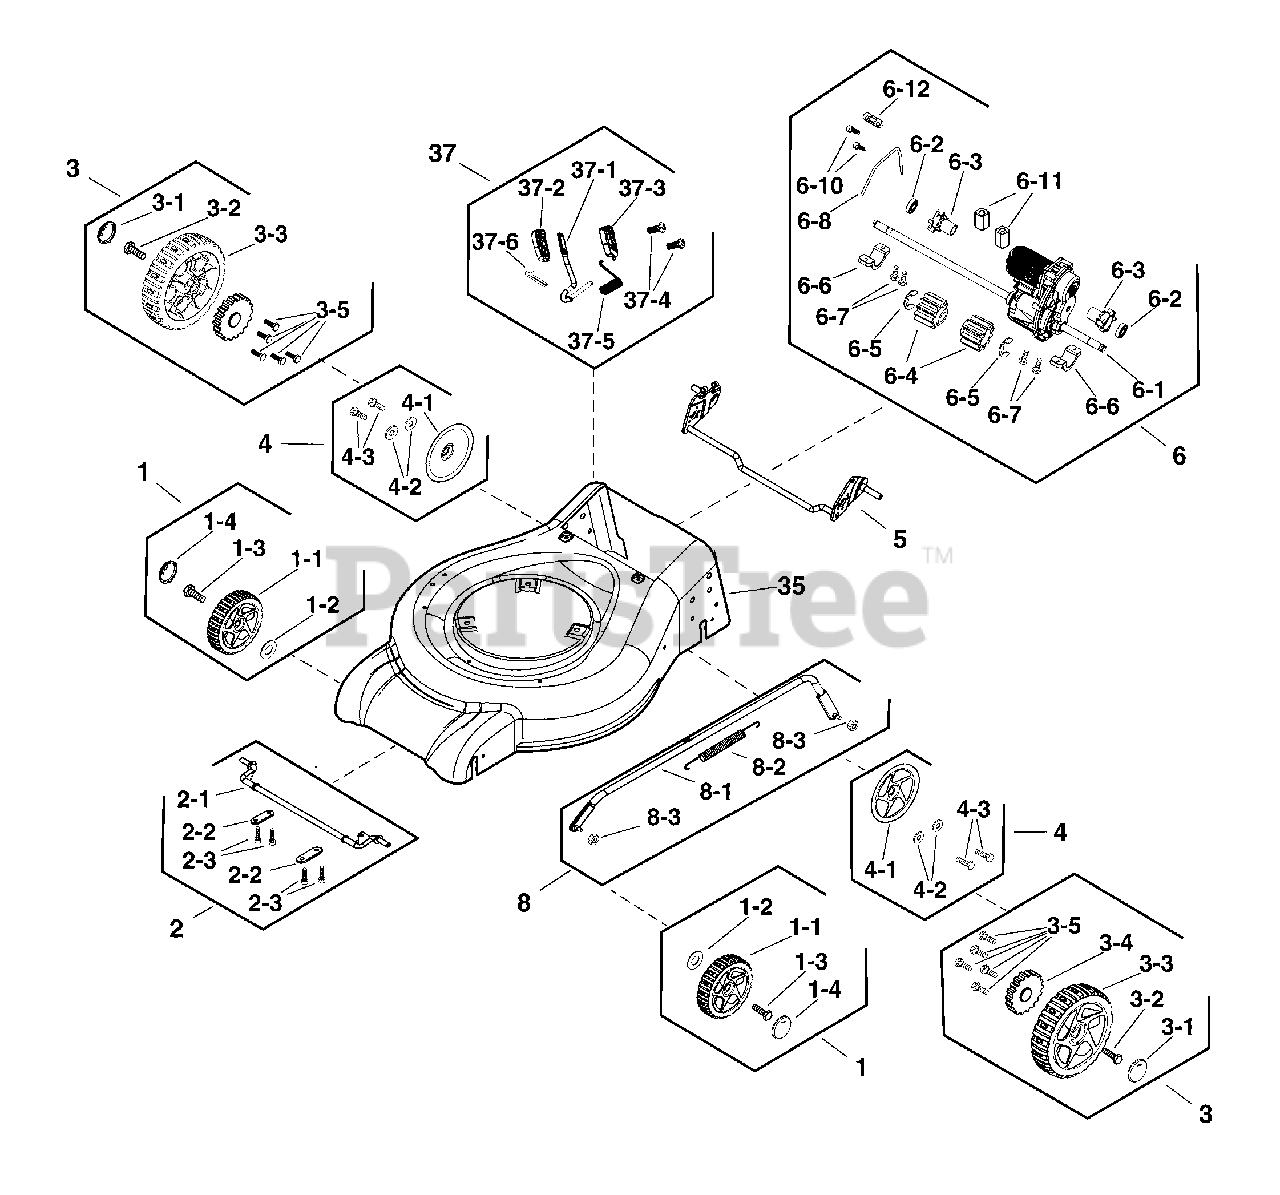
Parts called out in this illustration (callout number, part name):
1	KIT, Wheel, 8"
1-2	WASHER
1-3	BOLT
1-4	COVER, Wheel
2	KIT, FRONT AXLE
2-1	FRONT AXLE
2-2	TAB
3	KIT, Rear Wheel
3-1	COVER, Wheel
3-2	BOLT
3-4	GEAR, Drive
4	KIT, Dust Cover
4-1	DUST COVER
5	KIT, REAR AXLE
6	KIT, GEAR BOX
6-1	GT REDUCER
6-2	BEARING
6-3	COLLAR, Locking
6-4	GEAR, Drive
6-5	RING, Snap
6-6	PLATE, Axle
6-8	MOTOR CABLE
6-10	DISC, Tension
8	KIT, HEIGHT ADJUST ROD
8-1	CONNECTING ROD
8-2	SPRING
8-3	NUT
35	KIT, MOWER DECK
37	KIT, HEIGHT ADJUST
37-1	ADJUSTING ROD
37-2	HOUSING, Left
37-3	HOUSING, Right
37-5	SPRING
37-6	PIN, Cotter
